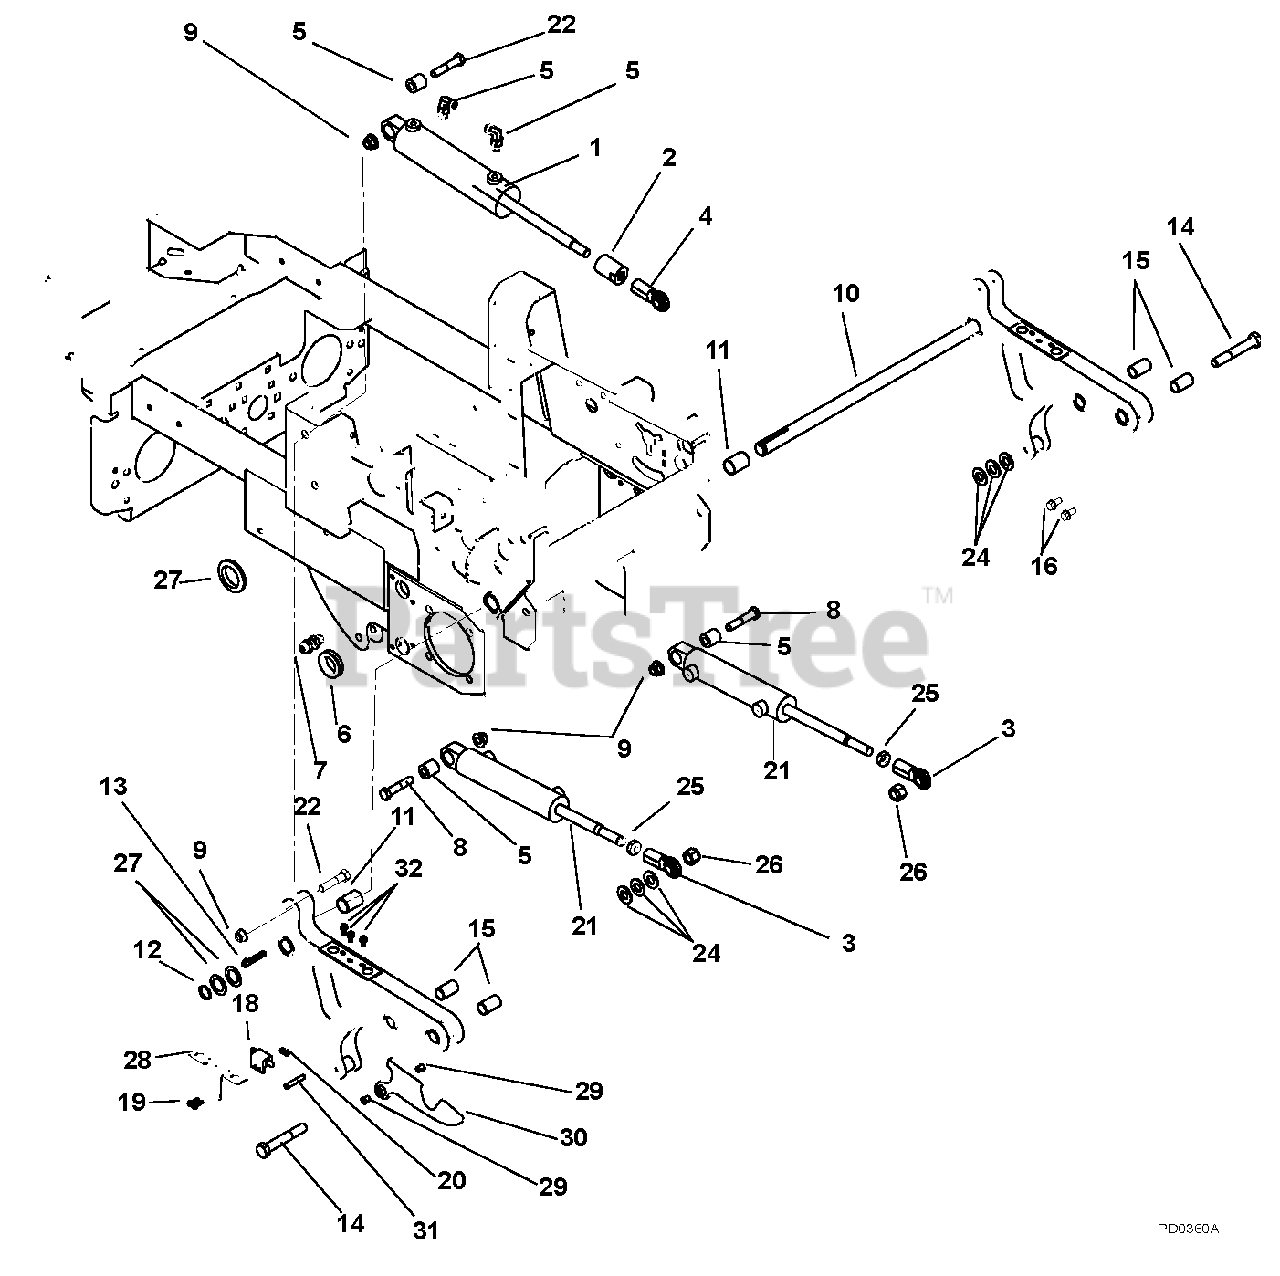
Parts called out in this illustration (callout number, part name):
1	Cylinder, Hydraulic Deck Lift
2	Spacer, Cylinder Stop 1.50 x 2.00
3	Rod End, 5/8 Right Hand - Female
4	Adapter, Hydraulic Fitting 90 M4F-M6O
5	Bushing, .516 x 1.000 x 1.050
6	Grommet, 1.25
7	Fitting, Hydraulic Bulkhead M4F-M4F
8	Bolt, Hex .50-13 x 2.25 Grade 5
9	Nut, .50-13 Nyloc Flange
10	Weldment, Main Arm Assembly w/Shaft
11	Bushing, 1.00 ID x 1.125 OD x 1.50
12	Ring, Retaining External 1.00 x .078
13	Key, Straight .25 x 1.50
14	Bolt, Hex .62-11 x 4.0 Grade 5 YWZC
15	Bearing, .75 x .875 x 1.50
16	Screw, Tapping .38-16 x .75 Hex Washer Head Thread Rolli
18	Switch, Single Pole N.O.
19	Screw, Machine 10-24 x .75 Hex Washer Head
20	Nut, Locking Nylon 10-24 with Insert YWZC
21	Cylinder, Hydraulic Lift
22	Bolt, Hex .50-13 x 2.50 Grade 5
23	Grommet, 2.00"
24	Washer, Flat Steel .656 x 1.31 x .095 YWZ
25	Nut, Jam .625-18
26	Nut, Nyloc .625-11 YWZC
27	Washer, Hardened Thrust 1.00 x 1.55 x .03
28	Bracket, Switch
29	Bushing, Flange Split Nylon
30	Weldment, Rocker Arm Switch
31	Pin, Roll 5/16 x 7/8
32	Screw, Tapping Hex Washer HD .25-20 x .50
